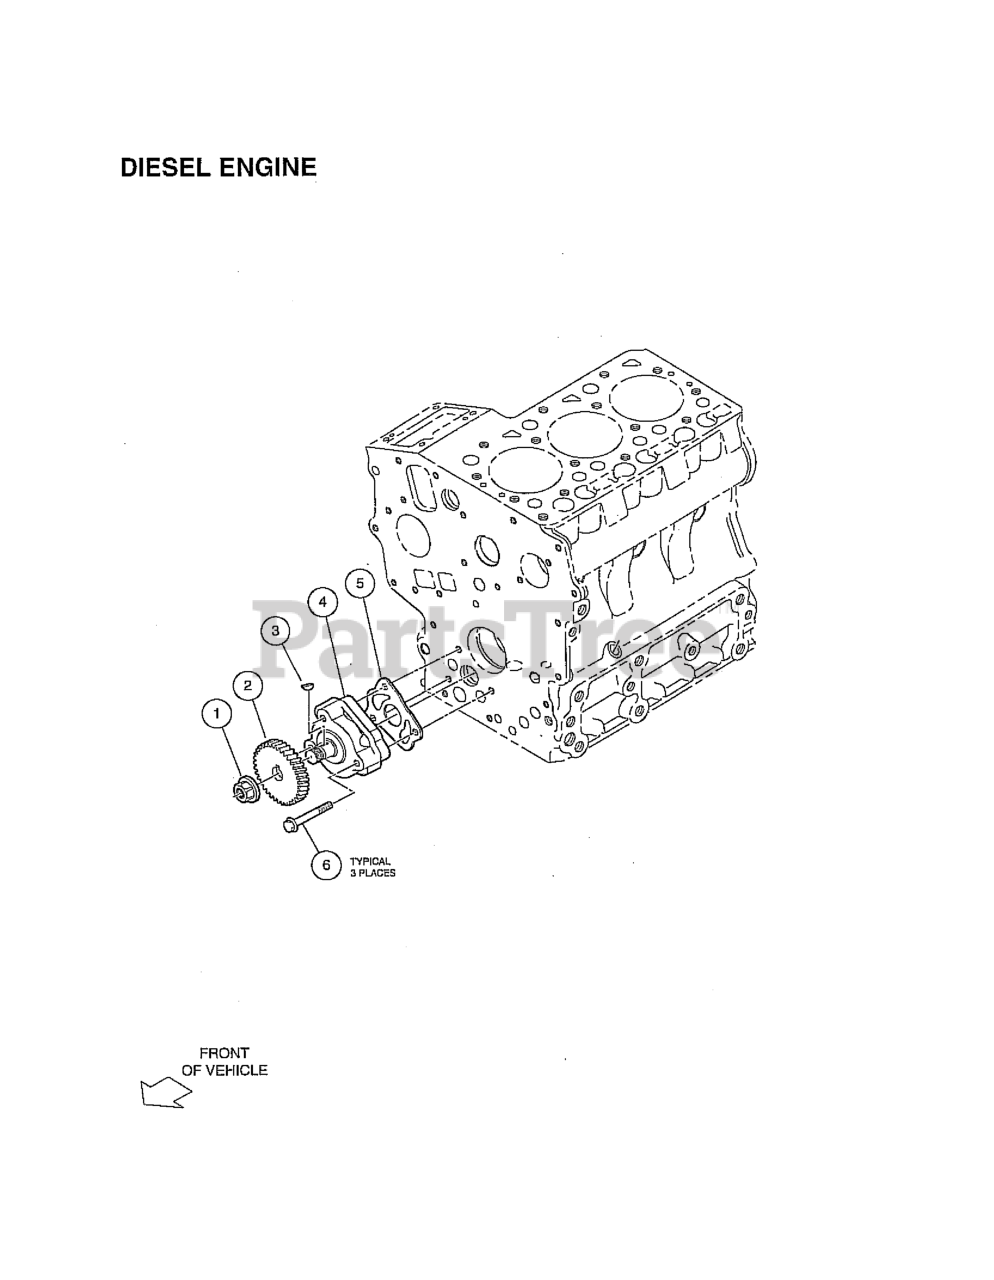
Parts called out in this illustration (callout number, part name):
1	WASHER, SPRING, M6
2	GEAR, OIL PUMP DRIVE
3	KEY, FEATHER, 8X4
4	ASSY, PUMP, OIL
5	GASKET, OIL PUMP NA
6	BOLT, OIL PUMP
